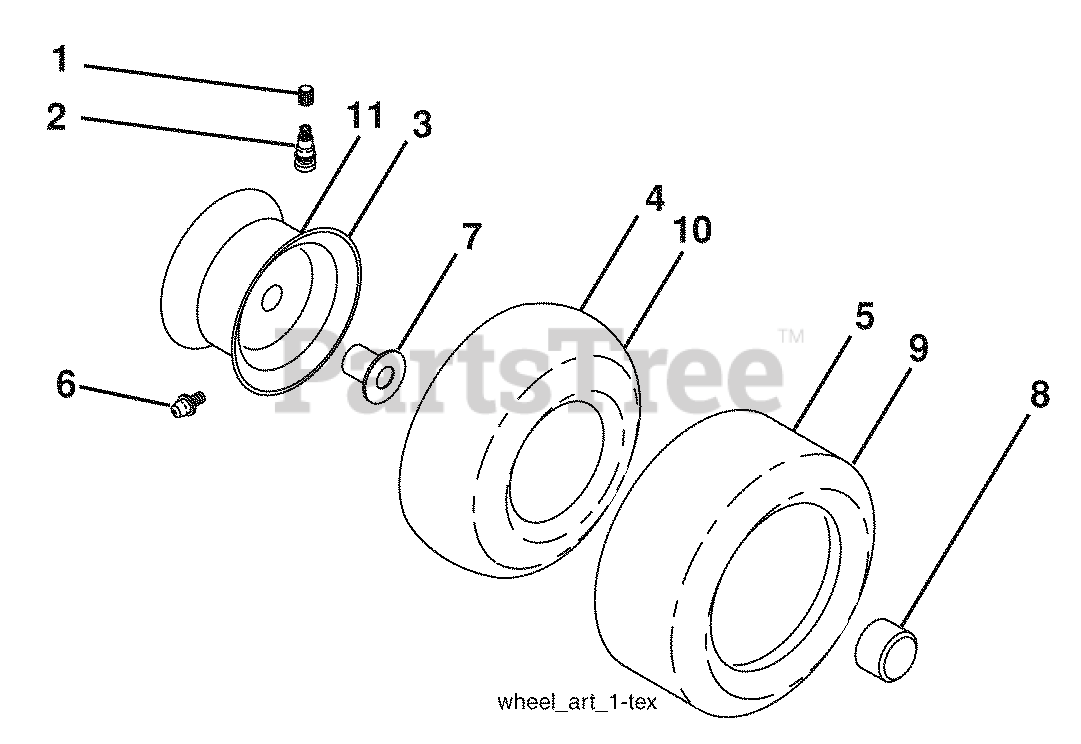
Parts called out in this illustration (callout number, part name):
1	Cap Valve Tire
2	Stem Valve
3	Rim Front
4	Tube Front
5	Tire Front 15 x 6.0-6
6	Fitting Grease
7	Bearing Flange
8	Cap Axle Blk 1 50 x 1 00
9	Tire R 18 x 9.5-8 Turf Saver LT
10	Tube Rear
11	Rim Asm 8" Rear
